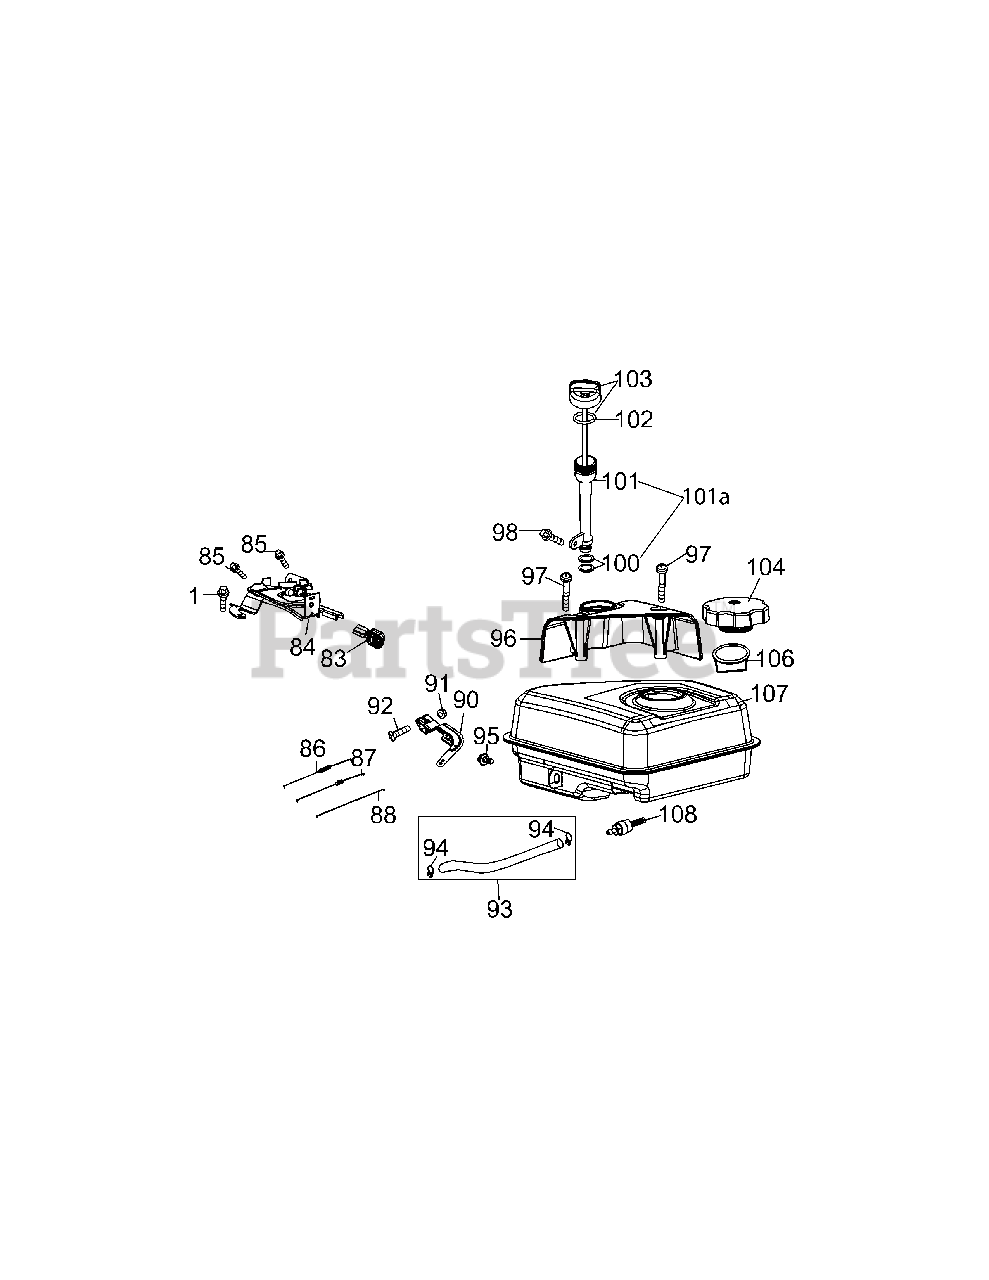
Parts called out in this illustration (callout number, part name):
1	Bolt M6×16
83	Throttle Control Knob
84	Primer Bracket
85	Bolt M6×12
86	Governor Spring
87	Throttle Linkage Spring
88	Throttle Linkage
90	Governor Arm
91	Nut M6
92	Governor Arm Bolt
93	Fuel Line Kit
94	Fuel Hose Clamp
95	Bolt M6×12
96	Dipstick Decoration Cover
98	Bolt M6×12
100	Oil Fill Tube O-Ring
101	Oil Fill Tube
102	Oil Fill Tube O-Ring
103	Dipstick Assembly
104	Fuel Cap Assembly
106	Fuel Level Indicator
107	Fuel Tank
108	Fuel Tank Nipple
